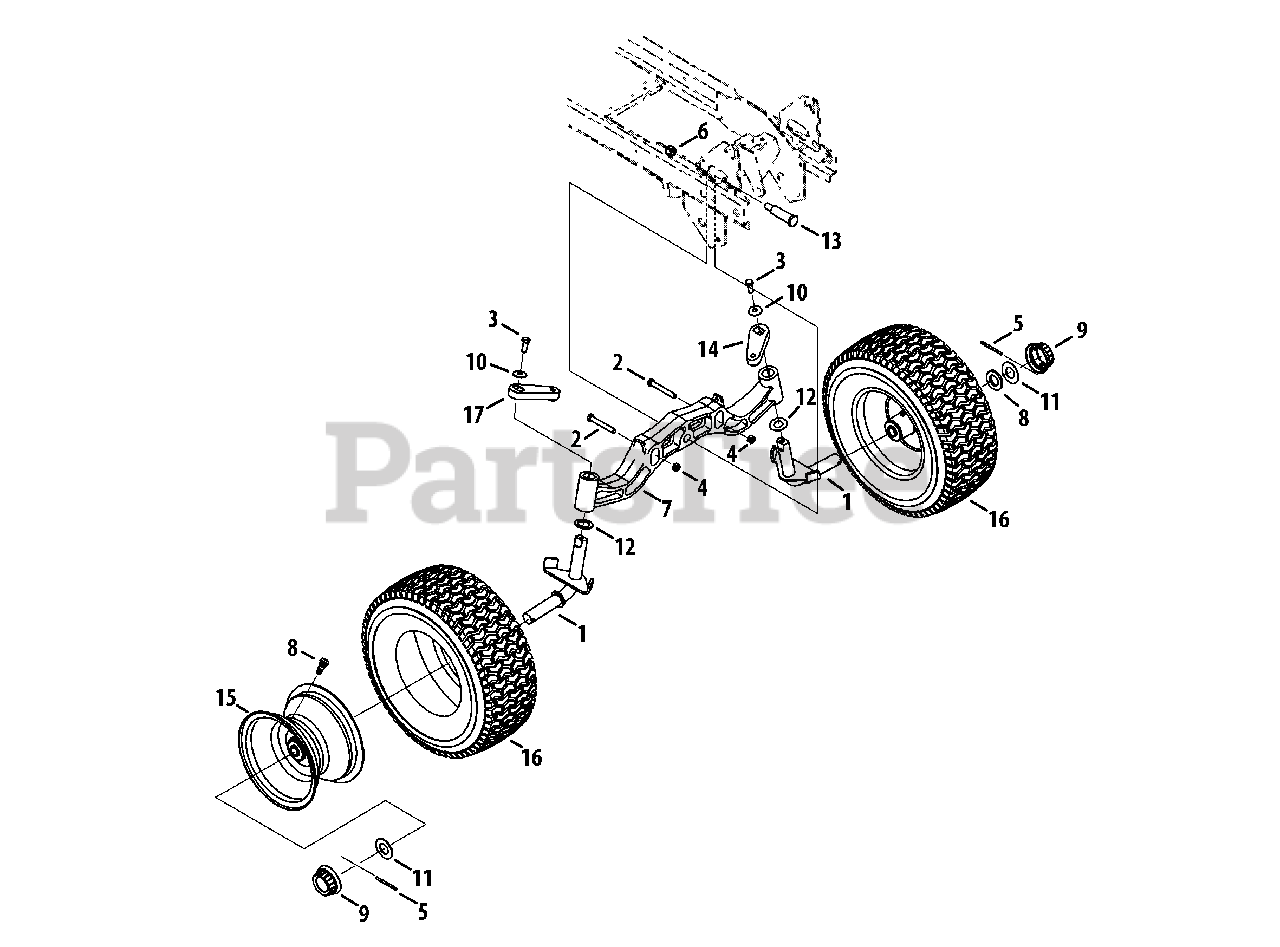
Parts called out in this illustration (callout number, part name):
1	Axle Assembly, 1"
2	Hex Screw, 3/8-16 x 2.75
3	Hex Cap Screw, 3/8-24 x 1.00
4	Hex Lock Nut, 3/8-16
5	Cotter Pin, 3/16 x 2.0
6	Hex Lock Nut, 1/2-13
7	Pivot Bar
8	Tubeless Air Valve
10	Bevel Washer, .390 x 1.130 x .062
11	Flat Washer, 1.05 x 1.92 x .06
12	Thrust Washer, 1.010 x 1.56 x .060
13	Shoulder Screw, .750 x 2.23
14	Steering Arm, LH
15	Rim Assembly, 16.0 x 6.5 x 8
16	Tire, 16.0 x 6.50-8.00
17	Steering Arm, RH
